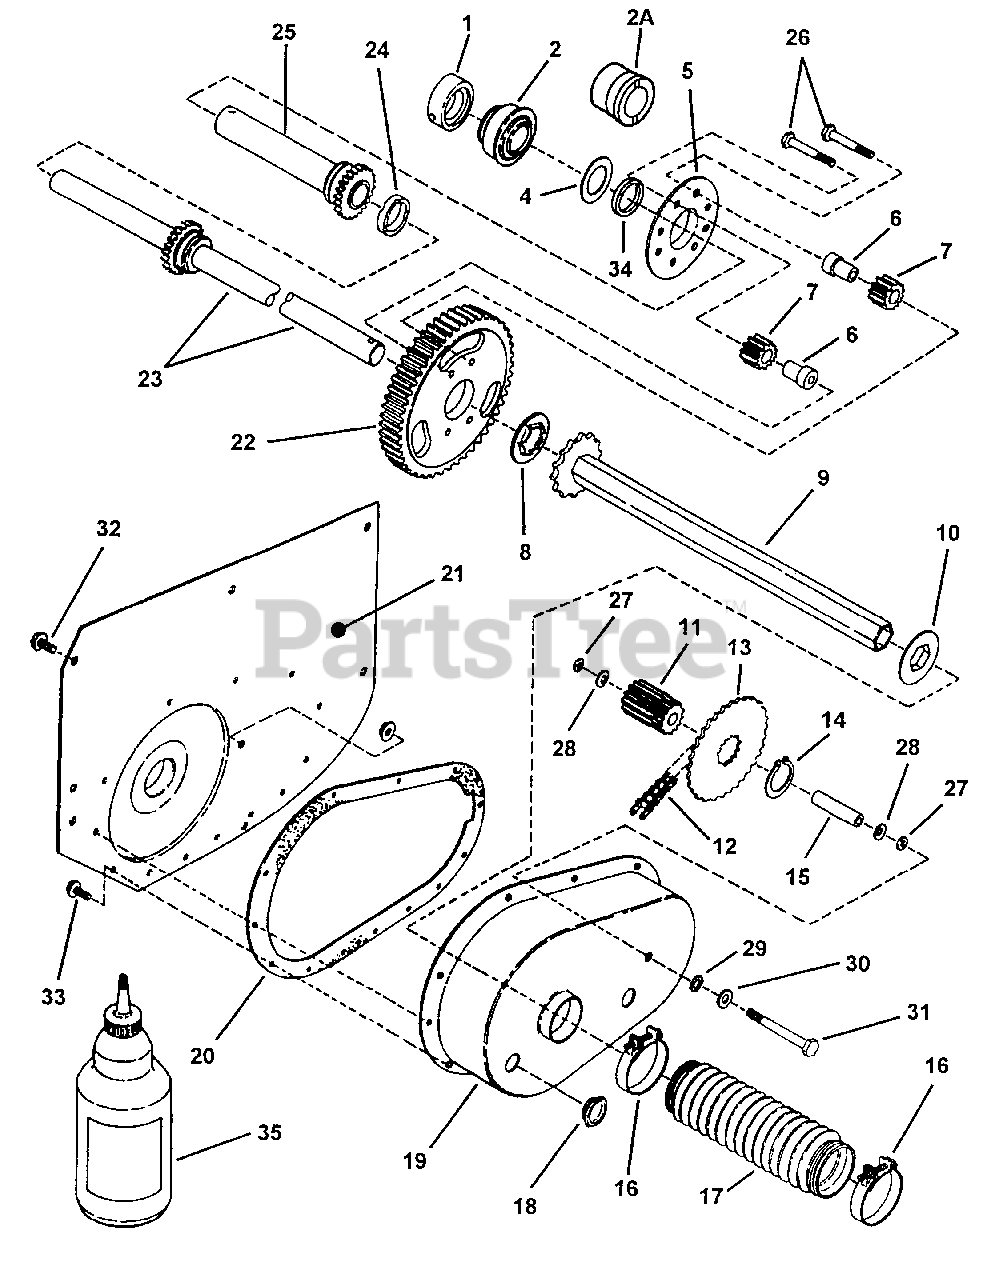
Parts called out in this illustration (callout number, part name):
1	COLLAR, Lock
2	BALL BEARING, Axle (R. H. Fender)
2A	BEARING, Axle (R. H. Fender)
3	NUT, 5/16-24 Hex Flange Lock
4	WASHER, Thrust
5	PLATE, Differential
6	SPACER, Pinion
7	GEARS, Differential Pinion
8	WASHER, Thrust
9	ASSEMBLY, Drive Hex Tube
10	WASHER, Hex Nylon Splash
11	GEAR, 11 Teeth-10 Pitch
12	CHAIN, 46 Pitch (#35)
13	SPROCKET
14	RING, Retaining
15	SPACER
16	CLAMP, Boot, 2"
17	BOOT, Oil Seal
18	PLUG, Oil Fill & Check
19	CASE, Transmission
20	GASKET, Transmission Case
21	FENDER, Right Hand
22	GEAR, 63 Teeth-10 Pitch
23	AXLE, Long
24	SPACER, Differential (1.25" ID x .425 Wide)
25	AXLE, Short
26	SCREW, 5/16-24 x 1-5/8" Hex Cap Special Lock
27	O-RING, 5/16"
28	WASHER, Belleville
29	WASHER, 5/16 External Tooth Lock
30	WASHER, 5/16 Flat
31	BOLT, 5/16-24 x 2-5/8" Idler
32	SCREW, 5/16-18 x 5/8" Self-Tapping
33	SCREW, 1/4-20 x 5/8" Self-Tapping
34	SPACER, Short Axle
35	GREASE, Transmission
